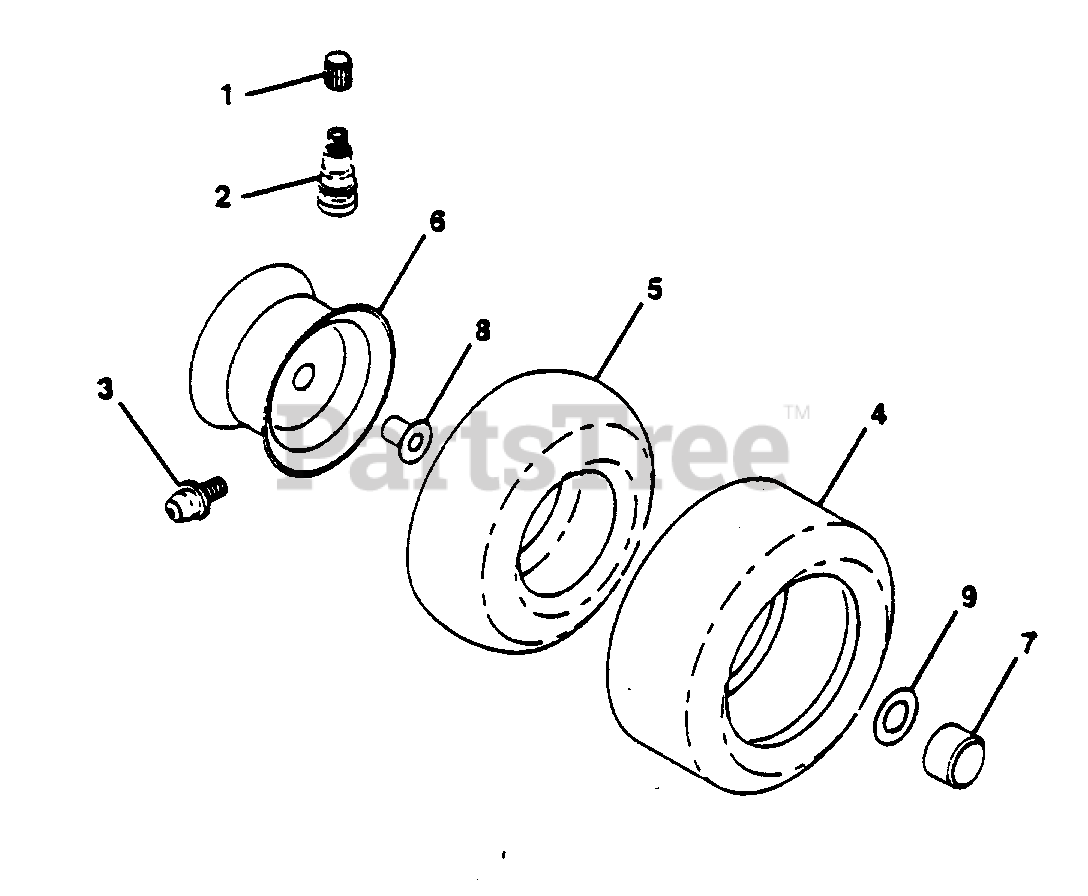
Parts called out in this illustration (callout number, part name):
1	Cap, Valve Stem
3	Fitting, Grease (Front Wheels Only)
4	Tire, Front
5	Tube, Front Tire (Optional - Service Item Only)
6	Rim, Front
8	Bearing Flange
9	Washer 25/32 x 1-5/8 x 16 Gauge
